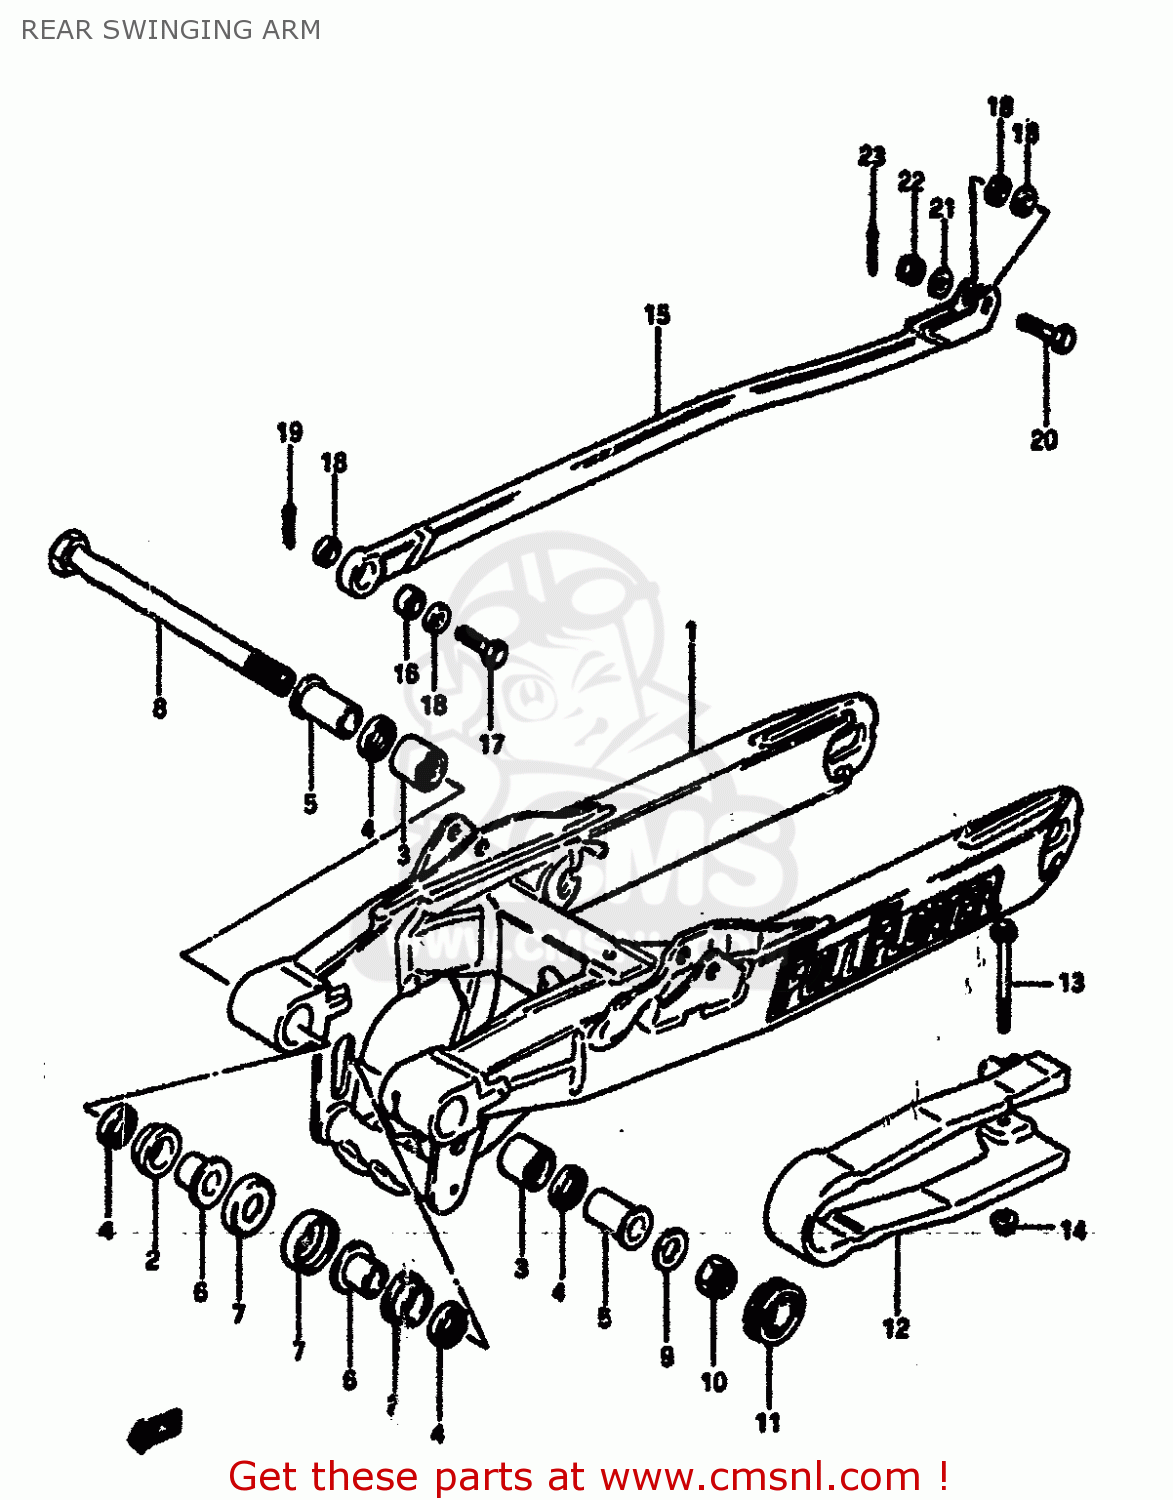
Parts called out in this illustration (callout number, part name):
1	SWING ARM ASSEMBLY,REAR
2	BUSH,RR SWINGINGARM PIVOT
3	BEARING(20X27X20)
4	OIL SEAL
5	SPACER,RR SWGARM PIVOT
6	SPACER,RR SWGARM PIVOT INNER
7	COVER,RR SWGARM DUST SEAL
8	SHAFT,REAR SWING ARM
9	WASHER(14.2X24X2.3)
10	NUT
11	CAP
12	BUFFER,CHAIN TOUCH DEFENSE
13	BOLT (6X70)
14	NUT
15	LINK,REAR TORQUE
16	SPHERICAL BEARING,TORQUE
17	BOLT 8X28
18	19
19	PIN
20	BOLT 8X29.5
21	WASHER
22	NUT 8MM
23	PIN 20X20
